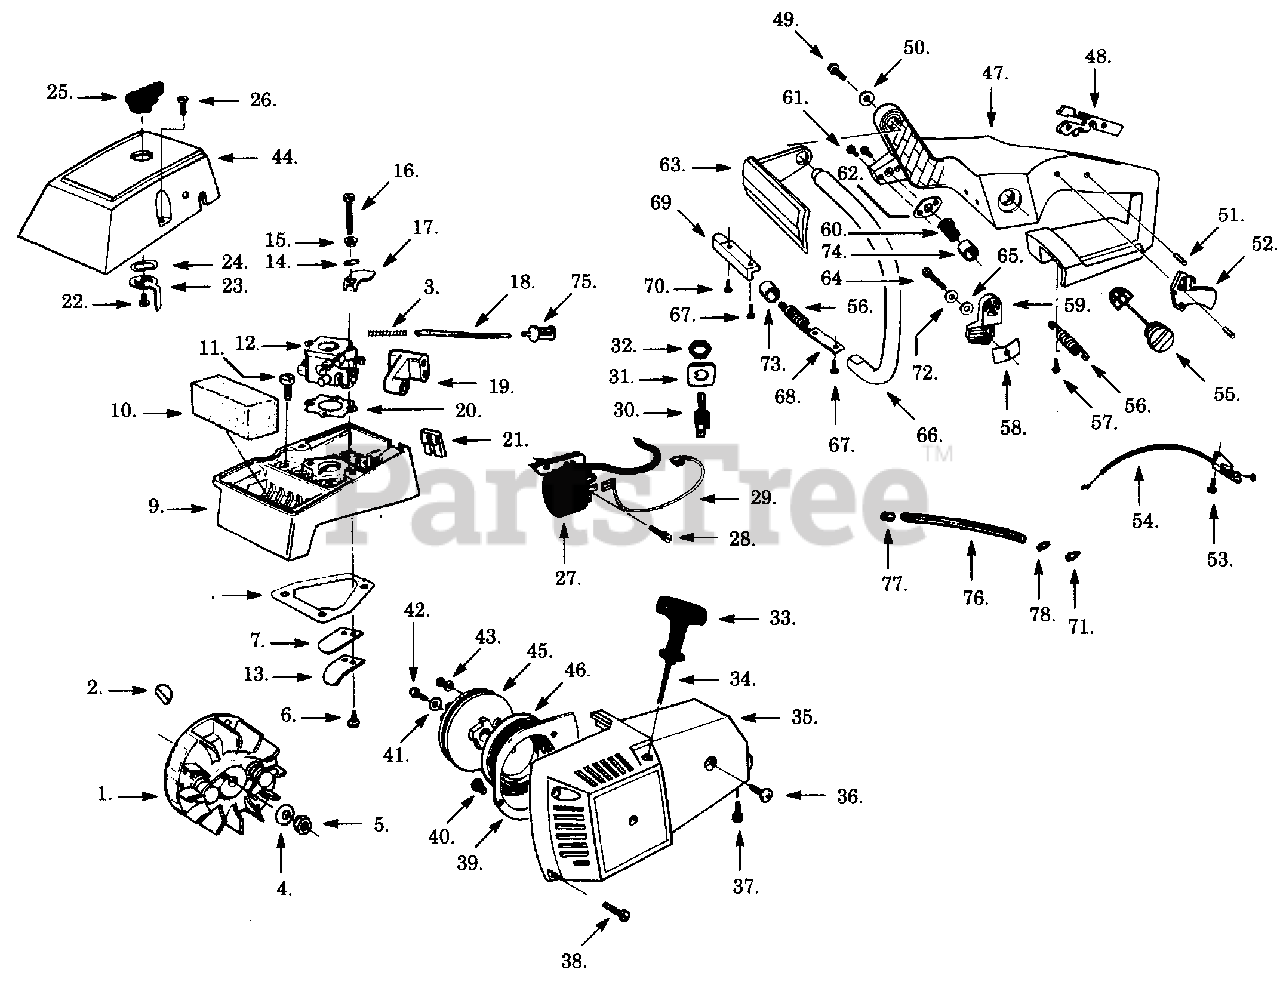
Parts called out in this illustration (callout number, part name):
1	Flywheel Ass'y.
2	Flywheel Key
7	Reed Valve
8	Gasket
9	Carburetor Hsg.
10	Air Filter
12	Carburetor
13	Reed Stop
14	Wave Washer
17	Choke Shutter
18	Line Kit (Bulk#8133)
19	Carb. Adj. Grommet
20	Carb. Gasket
21	Grommet - Throttle Cable
23	Choke Lever
24	Wave Washer
25	Choke Knob
27	Ignition Module
29	Wire Harness
30	Toggle Switch
31	Indicating Plate
32	Nut
33	Starter Handle
34	Rope Kit
35	Fan Hsg.
39	Fan Hsg. Baffle
42	Screw
43	Screw
44	Carb. Cover
45	Starter Pulley
46	Recoil Spring
47	Tank & Handle Assy
48	Throttle Lockout Lever
51	Roll Pin
52	Throttle Trigger
54	Throttle Cable Assy
55	Fuel Cap Assy.
56	Rear Mount Spring
58	Isolator Pad
59	Upper Bracket
62	Isolator Plate
63	Handguard
66	Front Handle
68	AV Strap
69	Isolator Bracket
71	Check Valve
72	Lockwasher
73	Isolator Sleeve
74	Upper Sleeve
75	Fuel Filter Assy
76	Vent Line Kit
77	Vent Plug
78	Vent Fitting
